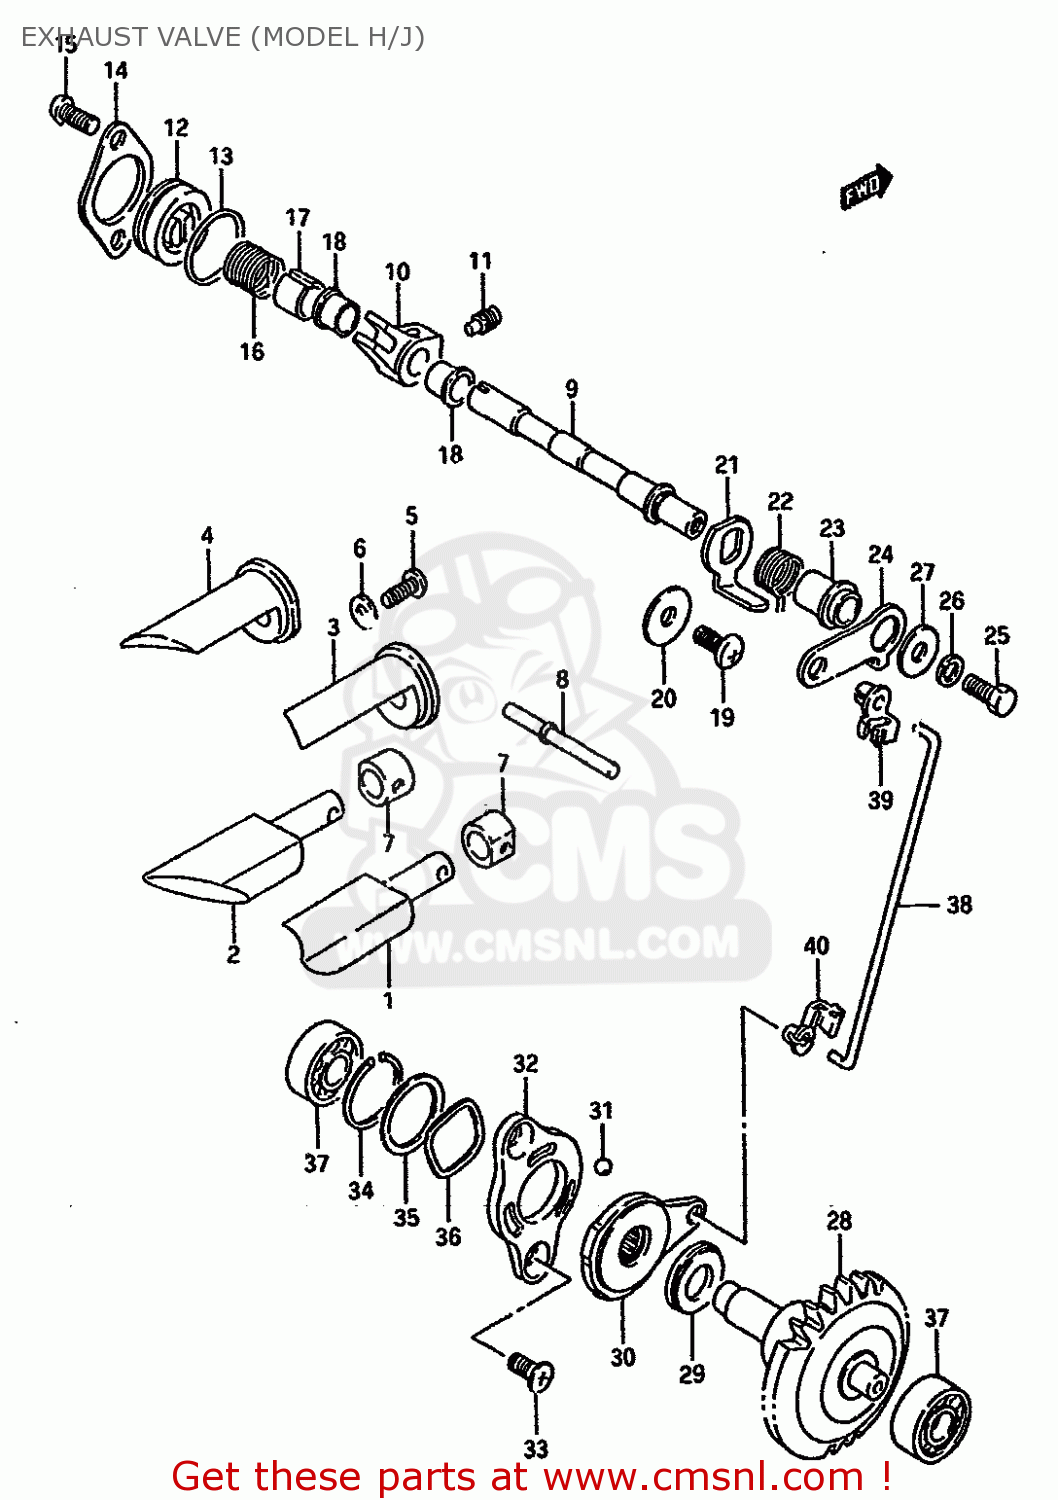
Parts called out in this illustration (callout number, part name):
1	VALVE,EXHAUST,R
2	VALVE,EXHAUST,L
3	GUIDE,EXHAUST VALVE
4	GUIDE,EXHAUST VALVE LH
5	SCREW
6	WASHER
7	SPACER,EXHAUST VALVE
8	PIN,EXHAUST VALVE. 43.6MM
9	SHAFT,EXHAUST VALVE
10	ARM,EXHAUST VALVE SHAFT
11	SCREW
12	CAP,EXHAUST VALVE
13	O RING(D:1.9,ID:22.6)
14	RETAINER,EXHAUST VALVE
15	SCREW
16	SPRING
17	SPACER,EXHAUST VALVE SPRING
18	BUSH
19	SCREW
20	WASHER
21	LEVER,EXHAUST VALVE NO
22	SPRING
23	SPACER,EXHAUST VALVE
24	LEVER,EXHAUST VALVE NO
25	BOLT
26	LOCK WASHER
27	WASHER (5.5X16X1.2)
28	GOVERNOR ASSEMBLY,EXHAUST
29	BEARING(10X22X2.8)
30	ACTUATOR,EXHAUST VALVE
31	BALL
32	STARTER,EXHAUST VALVE ACTUATOR
33	SCREW 5X12
34	CIRCLIP
35	SHIM(19.1X25X0.3)
36	WASHER
37	BEARING(8X22X7)
38	ROD,EXHAUST VALVE
39	BUSH,EXHAUST VALVE ROD NO.1
40	BUSH,EXHAUST VALVE ROD NO.2
